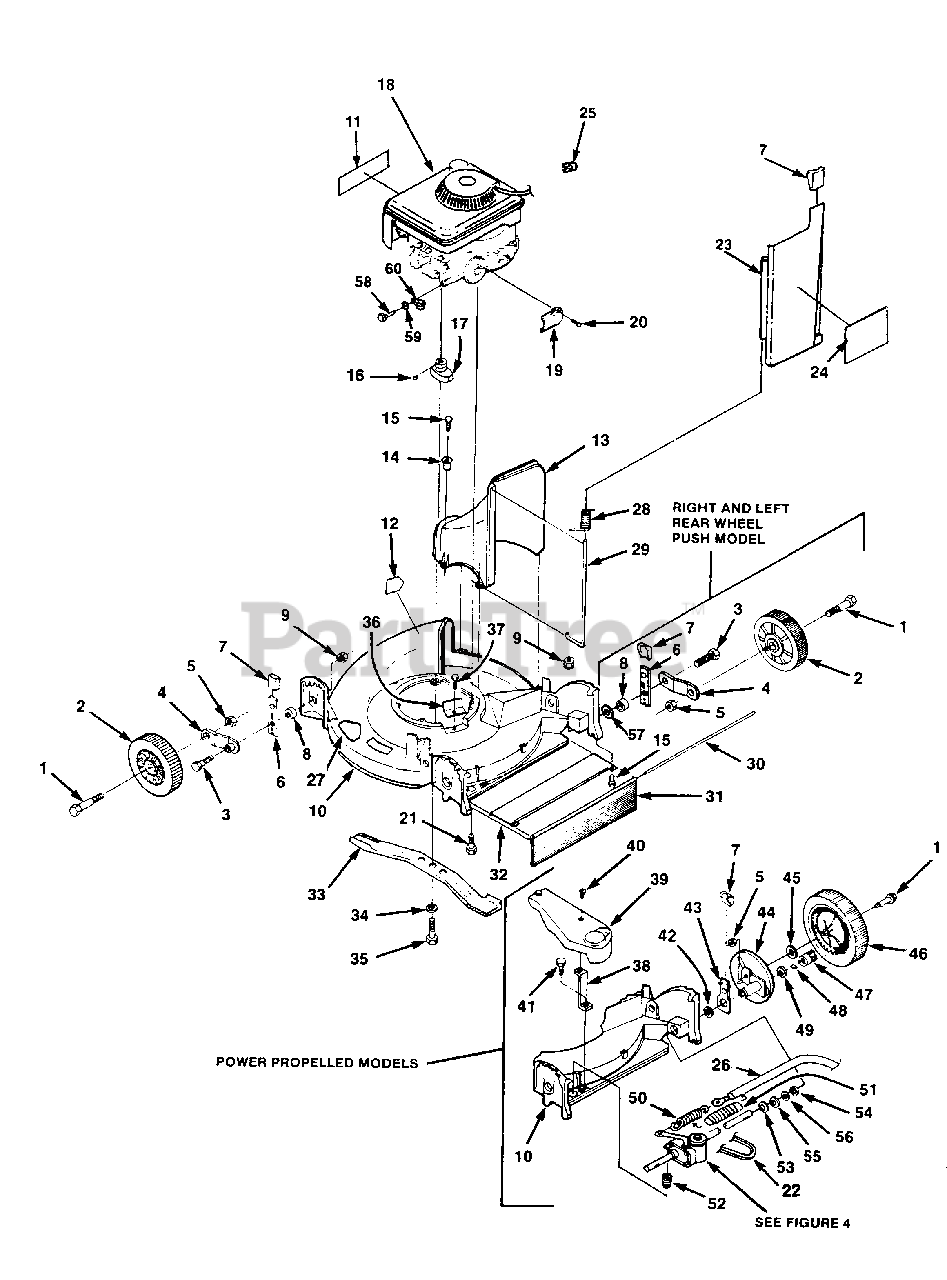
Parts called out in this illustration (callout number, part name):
1	BOLT- Axle
2	WHEEL & TIRE
3	BOLT- Hex hd. 5/16-18
4	ARM- Wheel hgt. adjusting
5	NUT- Hex 3/8-16
6	SPRING- Index
7	KNOB- Indexing spring
8	SPACER- Index spring
9	NUT- Flange 5/16-18
10	DECK- 21"
11	DECAL- Gasohol
12	DECAL- Warning
13	CHUTE- Discharge
14	STIMPSON EYELET
15	SCREW- Hex hd. 1/4-20 x 3/4
16	KEY- 5/8 x 5/32
17	ADAPTER- Blade
18	ENGINE- 3.5 H.P.
19	DEFLECTOR- Muffler
20	SCREW- Hex hd. 8-32 x 3/8
21	SCREW- 3/8-16 x 1 1/2
22	BELT- Drive
23	DOOR- Chute
24	DECAL- Door
25	STOP- Rope
26	CABLE- Traction
27	DECAL- Foot pad
28	SPRING- Door
29	PIN- Hinge
30	ROD- Drag flap
31	FLAP- Drag
32	COVER- Rear
33	BLADE- 21"
34	WASHER- Lock 7/16
35	BOLT- Shoulder
36	COVER- Belt opening
37	SCREW- Hex hd. 1/4-20 x 1/2
38	SUPPORT
39	COVER- Drive
42	SPACER- Hgt. Adj.
43	SPRING- Index
44	DRIVE WHEEL SUPPORT
45	WASHER- Flat
46	WHEEL & TIRE (drive)
47	PINION (R.H.)
48	PAWL- Pinion
49	WASHER- Flat
50	SPRING- Traction lever
51	COVER- Spring
52	SPRING- Compression
53	RING- Eaton
54	WASHER- Flat
55	WASHER
56	Washer - Shim
57	WASHER- Flat (5/16)
59	WASHER- Lock
60	CLAMP- Insulate
